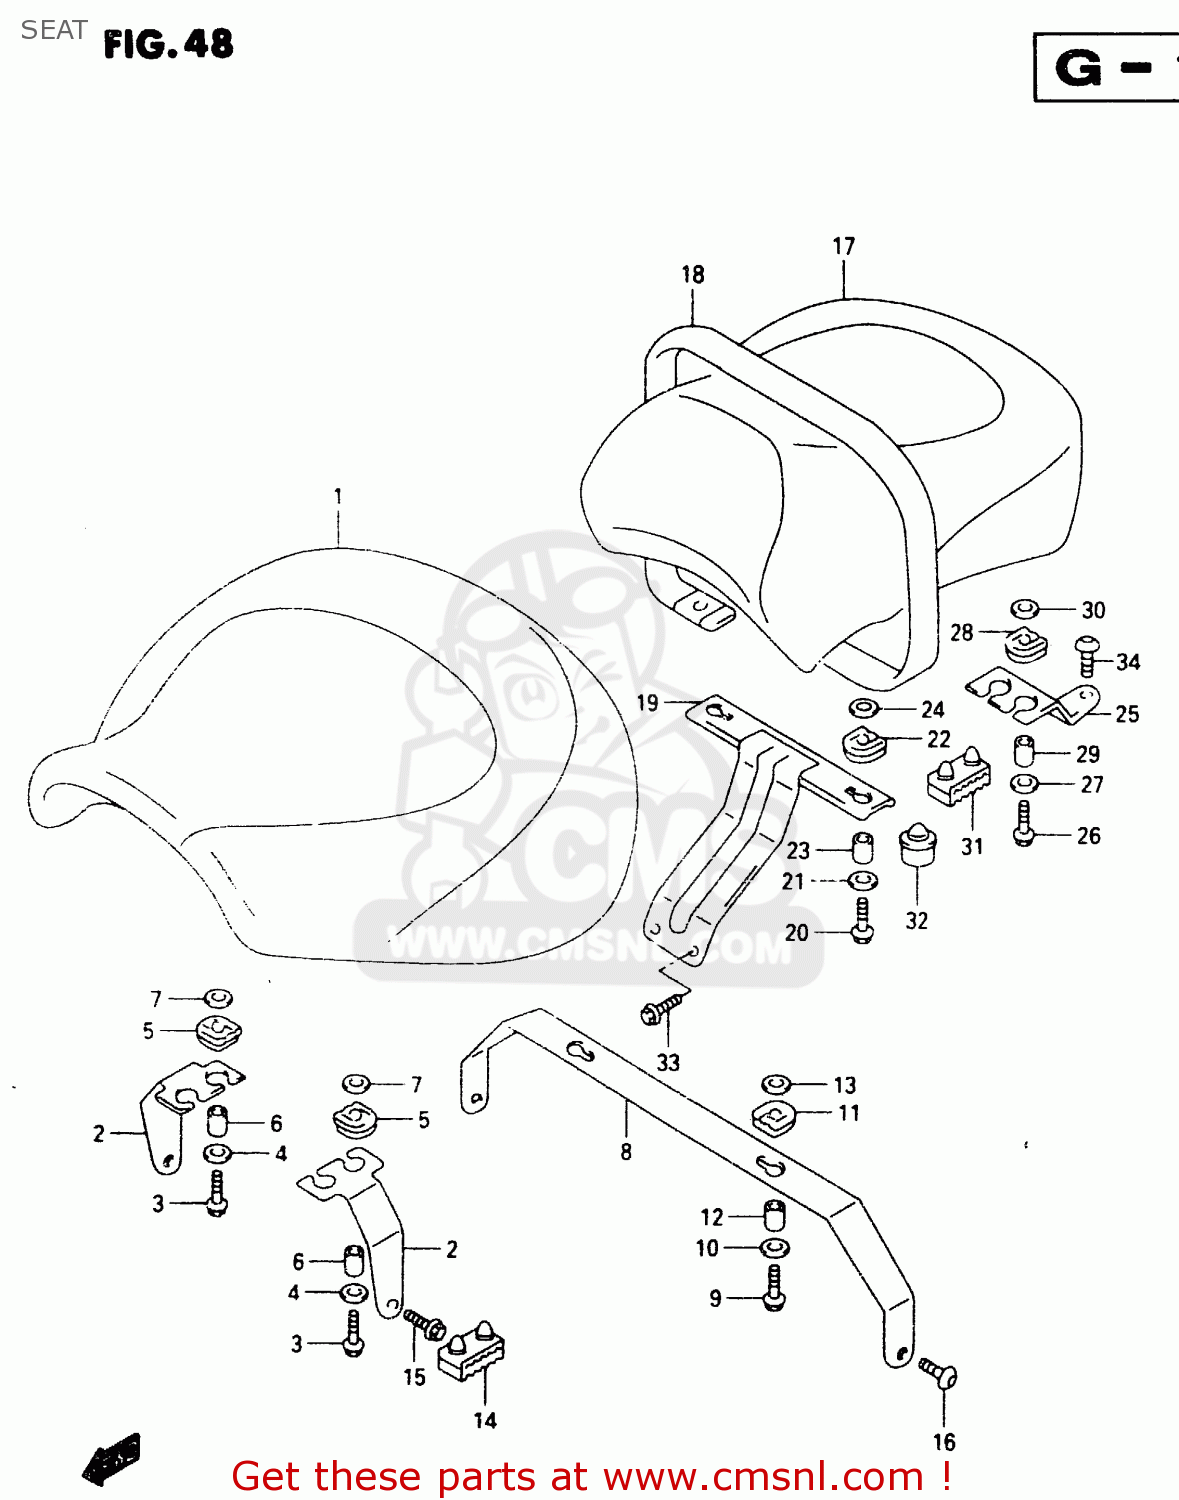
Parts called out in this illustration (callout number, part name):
1	SEAT ASSY(BLACK)
2	BRACKET,SEAT FR
3	BOLT
4	WASHER(6.5X20X1.6)
5	CUSHION
6	SPACER
7	WASHER(6.5X20X1.6)
8	BRACKET,SEAT RR
9	BOLT
10	WASHER(6.5X20X1.6)
11	CUSHION
12	SPACER
13	WASHER(6.5X20X1.6)
14	CUSHION,SEAT(40X20X15)
15	BOLT
16	BOLT(8X16)
17	SEAT ASSEMBLY,PILLION (BLACK)
18	BAND ASSY,PILLION SEAT(BLACK)
19	BRACKET,SEAT FR
20	BOLT
21	WASHER(6.5X20X1.6)
22	CUSHION
23	SPACER
24	WASHER(6.5X20X1.6)
25	BRACKET,SEAT RR
26	BOLT
27	WASHER(6.5X20X1.6)
28	CUSHION
29	SPACER
30	WASHER(6.5X20X1.6)
31	CUSHION,SEAT(40X20X15)
32	CUSHION
33	BOLT
34	BOLT(8X16)
